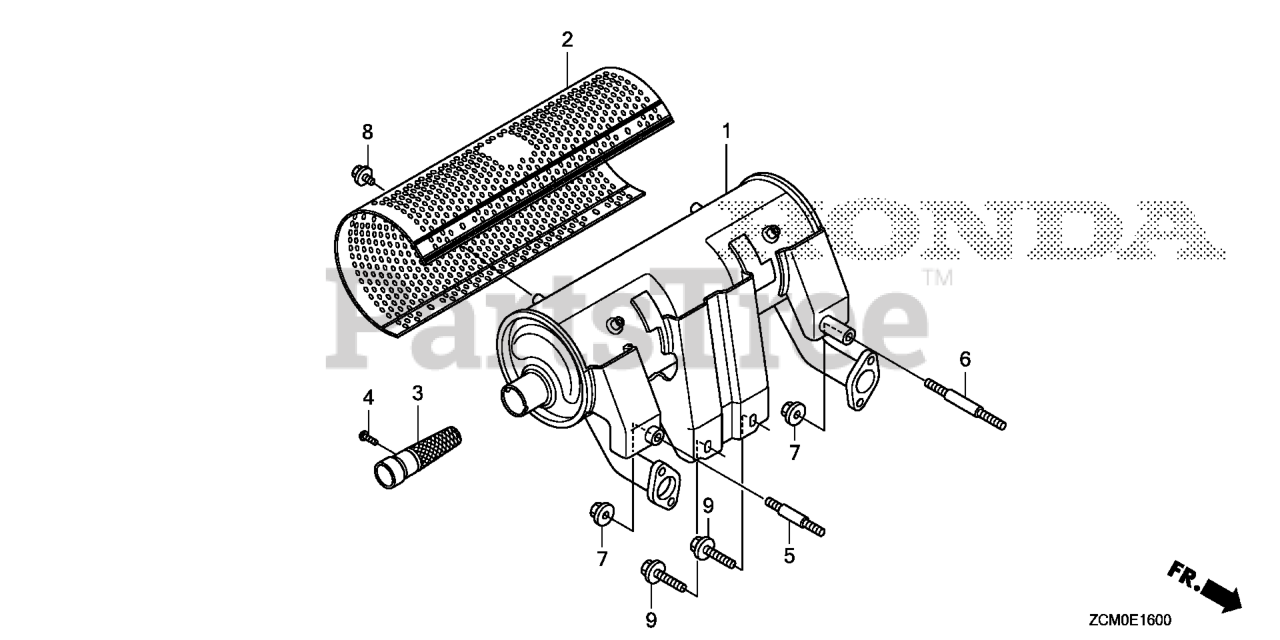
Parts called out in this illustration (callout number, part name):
1	MUFFLER (HIGH-R)
2	PROTECTOR, MUFFLER (HIGH) (FUTABA)
3	ARRESTER, SPARK
4	SCREW, TAPPING (5X8) (FOR SILVER MUFFLER)
5	BOLT, STUD (8X45)
6	BOLT, STUD (8X60)
7	NUT, FLANGE (8MM)
8	BOLT, FLANGE (6X8)
9	BOLT, FLANGE (8X20) Use up to Engine SN 1609606.
